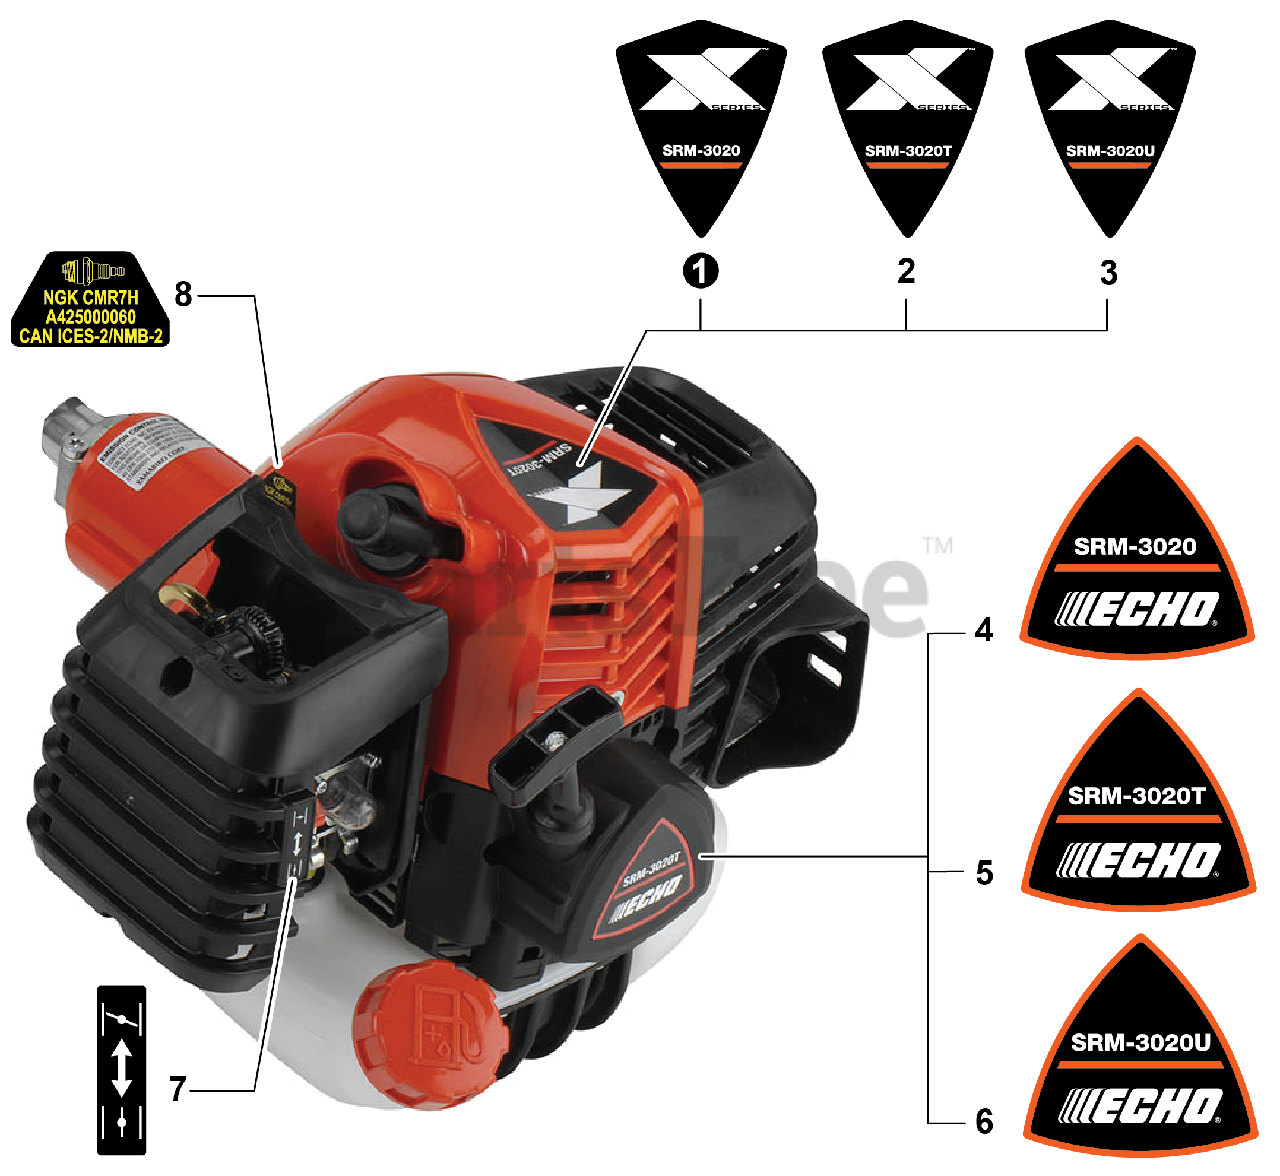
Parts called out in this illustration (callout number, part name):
1	LABEL - MODEL SRM-3020
2	LABEL - MODEL SRM-3020T
3	LABEL - MODEL SRM-3020U
4	LABEL, STARTER - SRM-3020
5	LABEL, STARTER - SRM-3020T
6	LABEL, STARTER - SRM-3020U
7	LABEL, CHOKE
8	LABEL, SPARK PLUG - CMR7H
